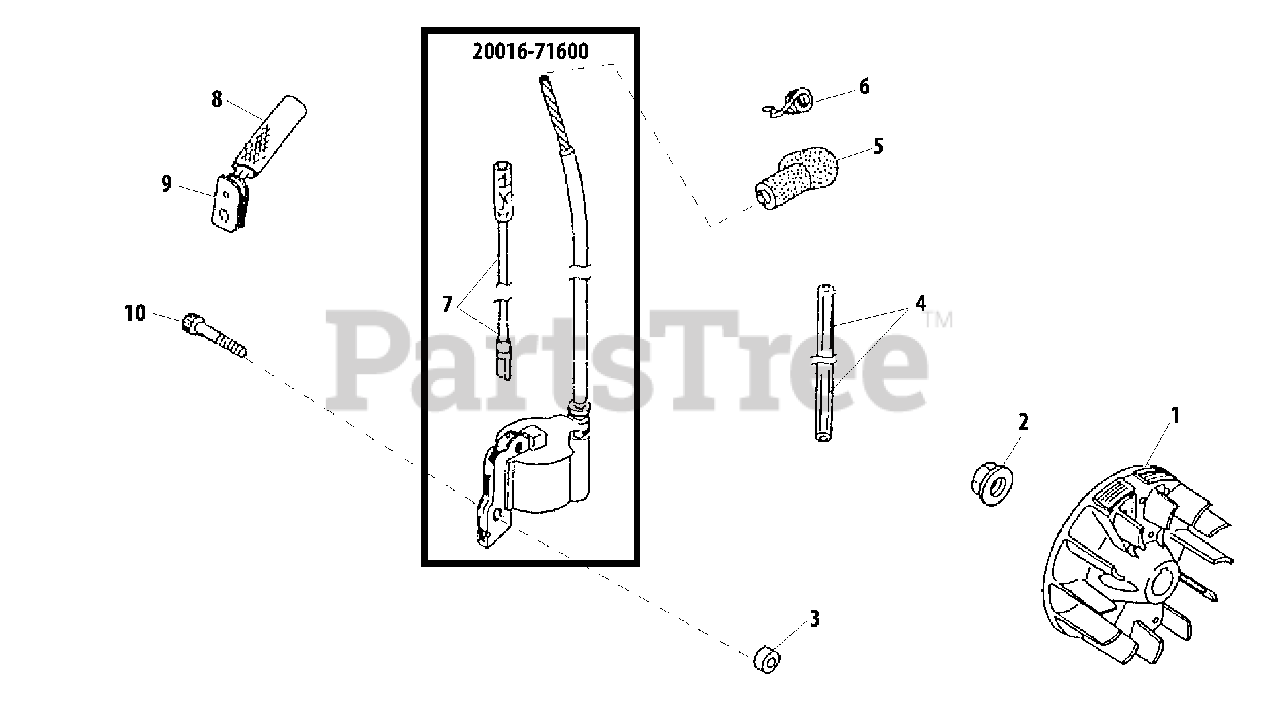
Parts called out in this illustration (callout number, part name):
1	FLYWHEEL
2	NUT - 8
3	INSULATOR
4	TUBE
5	CAP, SPARK PLUG
6	TERMINAL, SPARK PLUG CAP
7	LEAD - IGNITION
8	TUBE
9	GROMMET
10	SCREW - 4X26
20016-71600	IGNITION COIL ASSY
